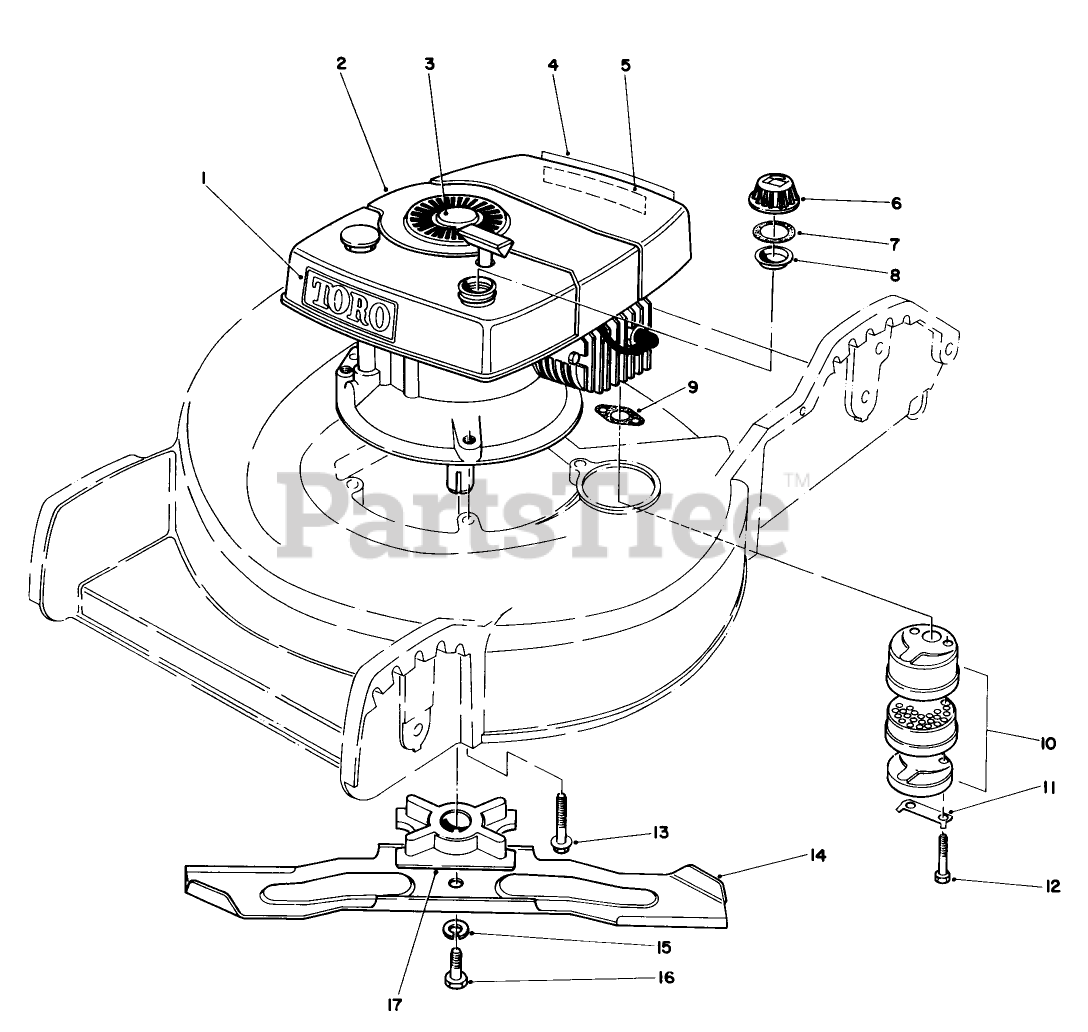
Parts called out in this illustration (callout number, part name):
1	Decal Tow
2	Engine
3	Plug Button
4	Decal-Primer
5	Decal Maintenance
6	Gas Cap Assembly (Incl Ref. #788)
7	GASKET
8	GAS CAP BAFFLE
9	MUFFLER GASKET
10	Muffler Assembly (Incl. Ref. #11 & 12)
11	CLIP - LOCKING
12	SCREW-HH
13	3/8-16 X 2 CAPSCREW
14	Blade
15	WASHER-LOCK
16	SCREW-HH
17	BLADE RETAINER
